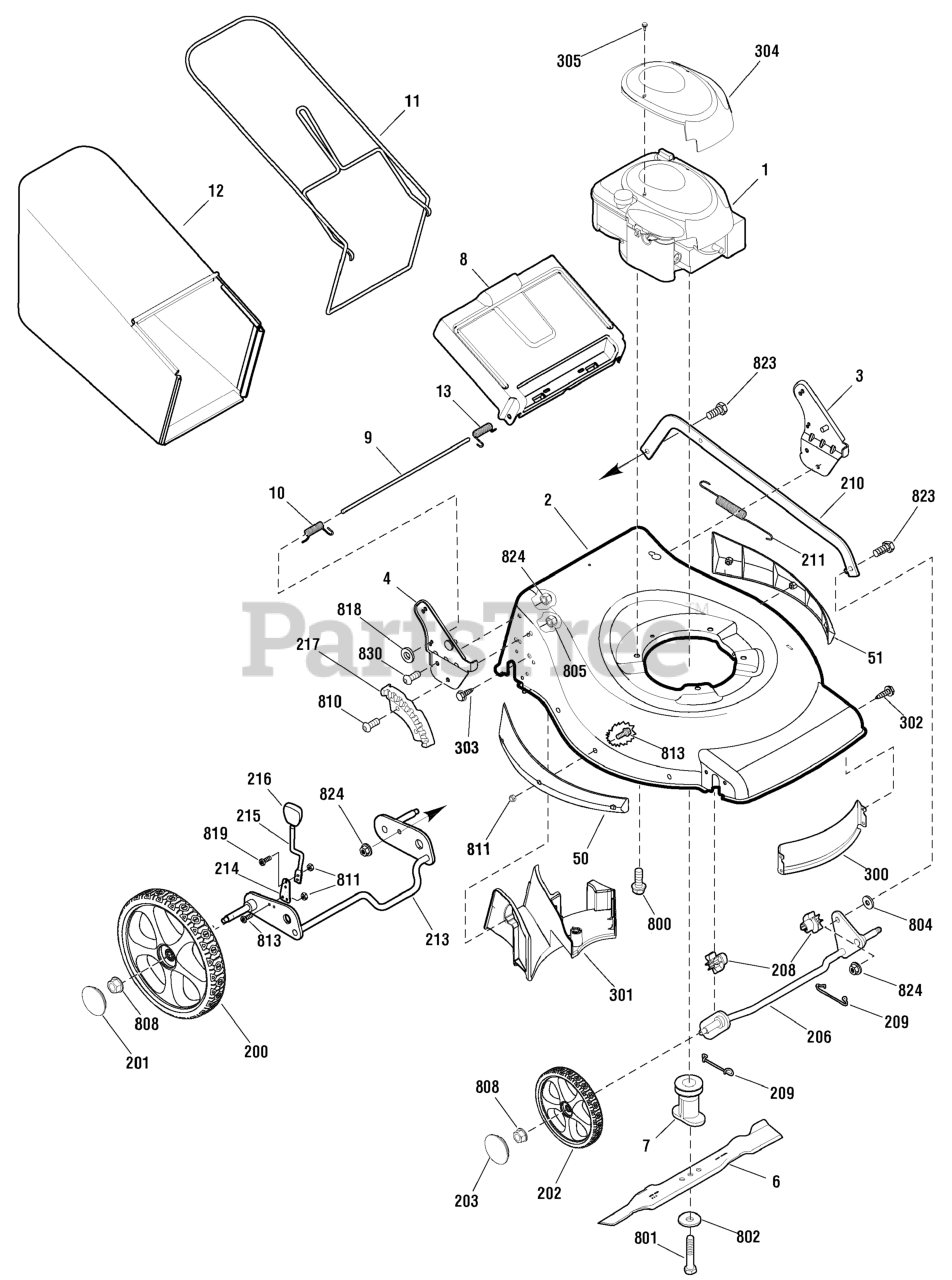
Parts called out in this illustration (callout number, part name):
1	* ENGINE, 6.25TP 625 Series Briggs & Stratton
1	* ENGINE, 6.5TP 650 Series Briggs & Stratton
1	* ENGINE, 8.5TP 850 Series Briggs & Stratton
1	* ENGINE, 8.5TP 850 Series, Briggs & Stratton
2	MOWER HOUSING
3	BRACKET ASSEMBLY, L.H.
4	BRACKET ASSEMBLY, R.H.
6	BLADE, 19"
7	BLADE ADAPTER ASSEMBLY
8	DOOR, Rear
9	ROD, Rear Door
10	SPRING, Torsion Rear Door, R.H.
11	FRAME ASSEMBLY
12	BAG ASSEMBLY
13	SPRING, Torsion Rear Door, L.H.
50	SIDE GUARD, R.H.
51	SIDE GUARD, L.H.
200	WHEEL, Rear
201	HUBCAP, Rear
202	WHEEL, Front
203	HUBCAP, Front
206	CROSSBAR ASSEMBLY, Front
208	BUSHING, Front Crossbar
209	SPRING, Clip Crossbar
210	LINK, Single Lever, High Wheel
211	SPRING, Extension
213	REAR CROSSBAR
214	SPRING, Adjuster
215	LEVER, Height Adjustment
216	KNOB, Adjuster
217	BRACKET, Height Adjuster
300	BAFFLE, Front, 19"
301	BAFFLE, Rear, 19"
302	SCREW, Pan Head, Taptite, 1/4-20 x 1/2
303	SCREW, Pan Head, Taptite, 1/4-15 x 5/8
304	SHROUD, With Label
305	CAPSCREW, Hex Washer Head
800	CAPSCREW, Hex Head, 3/8-16 x 1
801	BOLT, Blade, 3/8-24 x 2
802	WASHER, Belleville
804	WASHER, Wave
805	NUT, Nylock, M8 x 1-1/4
808	NUT, Flange, 3/8-16
810	BOLT, Hex Key Head
811	NUT, Nylock
813	SCREW, Torx Head, M5 x .8 x 14mm
818	PUSHNUT, 1/4
819	SCREW, Torx Head, M5 x .8 x 12.5mm
823	BOLT, Shoulder, 5/16-18 x 1
824	NUT, Flange, 5/16-18
830	CAPSCREW , 5/16-18 x 3/4
1000	DECAL KIT
